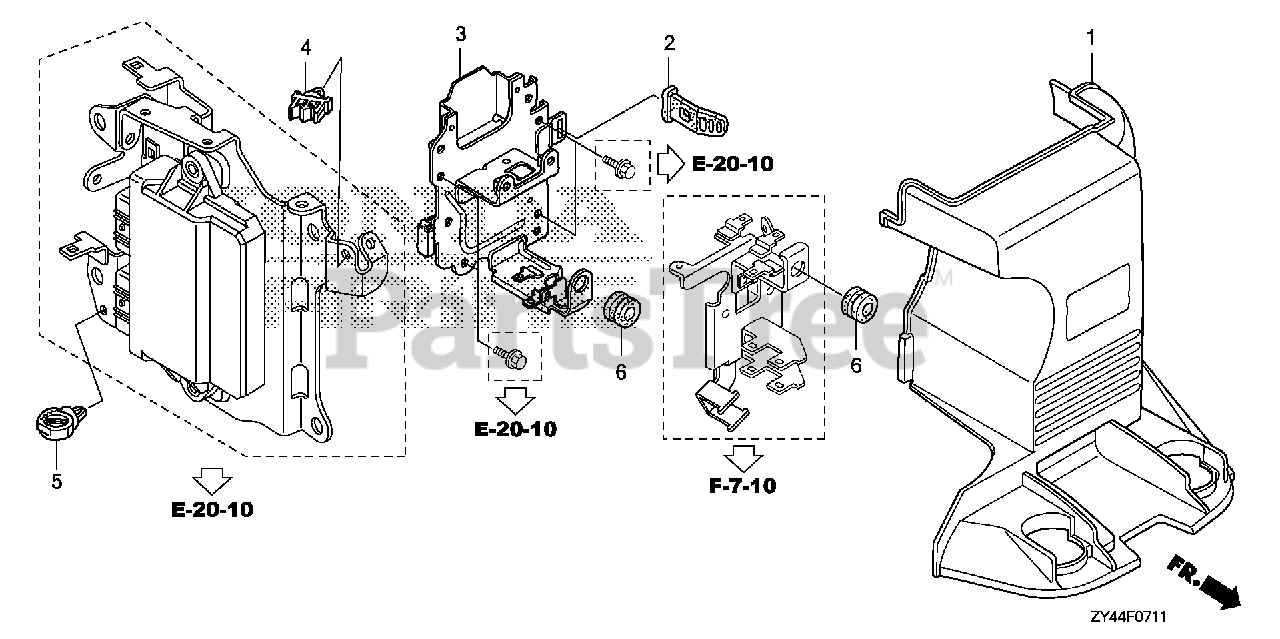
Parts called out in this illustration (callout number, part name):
1	COVER, ELECTRIC PARTS
2	BELT, COVER
3	BRACKET, ELECTRIC PARTS
4	CLIP, BRAKE PIPE
5	CLIP, WIRE HARNESS (25MM)
6	RUBBER, TANK CUSHION
